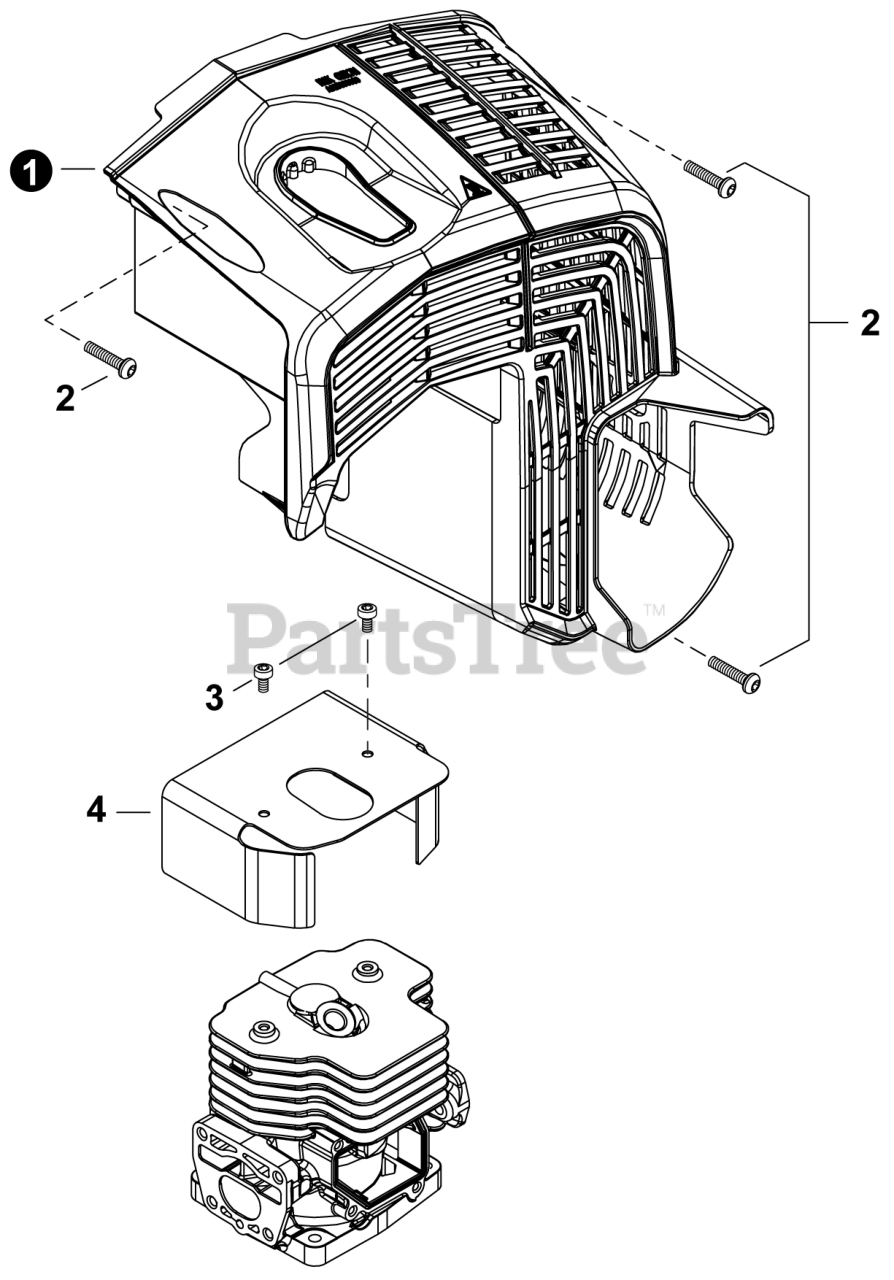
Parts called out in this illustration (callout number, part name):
1	COVER, ENGINE
2	BOLT, TORX 5x20
3	BOLT, TORX 4x10
4	COVER, CYLINDER
